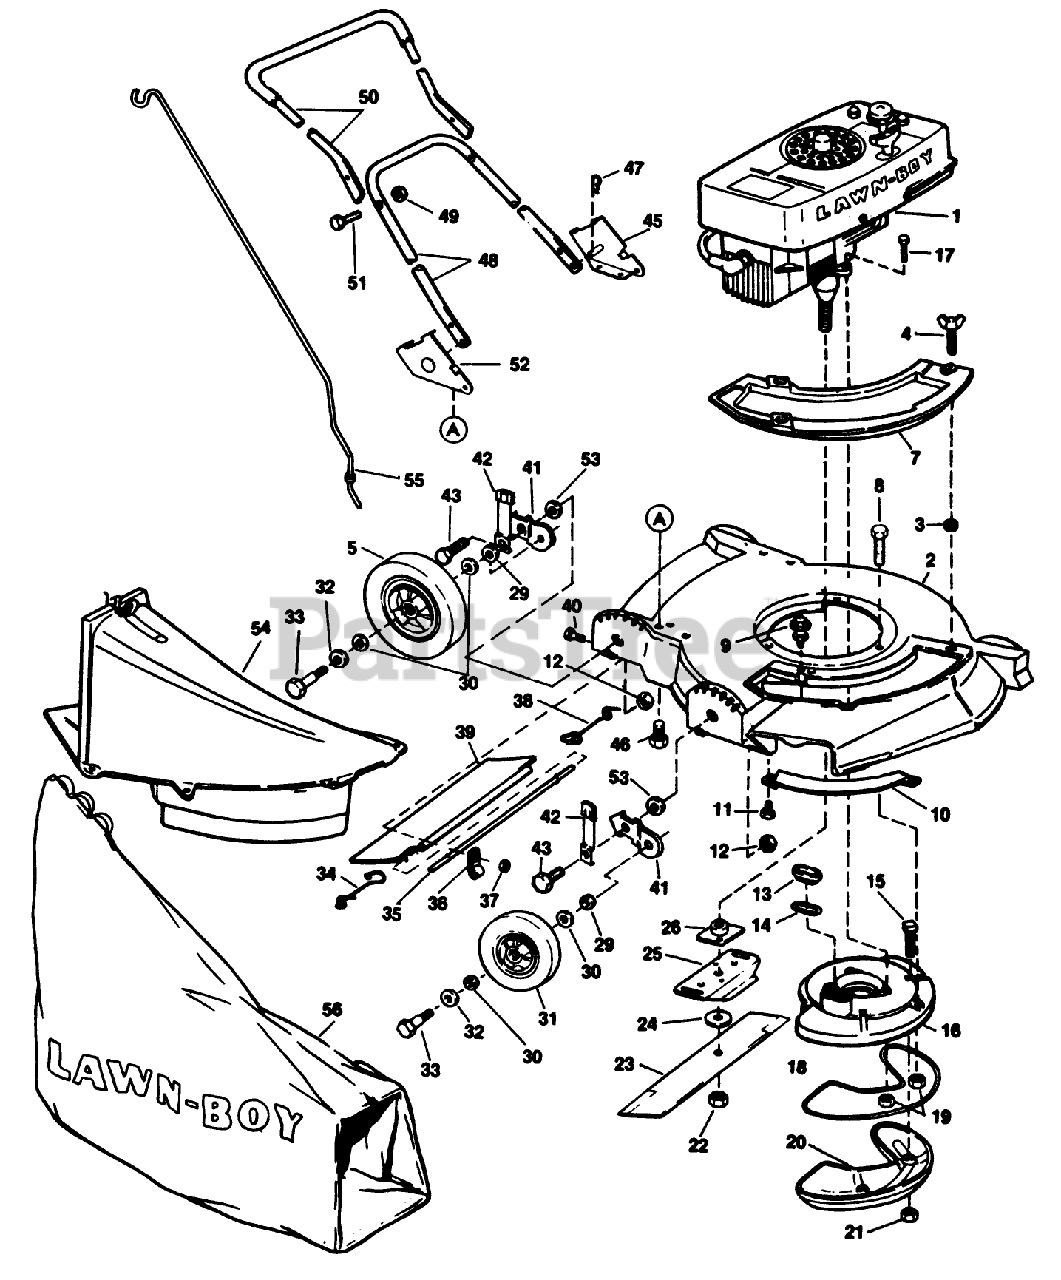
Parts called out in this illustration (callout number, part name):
1	See Page 34 for Engine, Magneto and Carburetor Parts List. See Note #2 at bottom of this page.
4	WING SCREW LAWRE
10	TOE BAR 19"
10	BAR-TOE
12	LOCKNUT
14	GASKET S
19	NUT-LOCK F
22	NUT-BLADE
24	WASHER
26	PLATE AND COLLAR ASM
29	WASHER WROUGHT
31	WHEEL & TIRE KIT
33	BOLT WHEEL
34	SPRING;TRAILING SHIELD RH
35	ROD T/SHIELD ADV WIRE
35	ROD 21" ADVANCE
36	CLAMP ROD KMC
38	SPRIG T/SHLD ASOC
47	HAIR PIN
49	Nut-Handle
54	Chute
55	ROD GRASSBAG
56	89802 LB WHOLE GOODS
